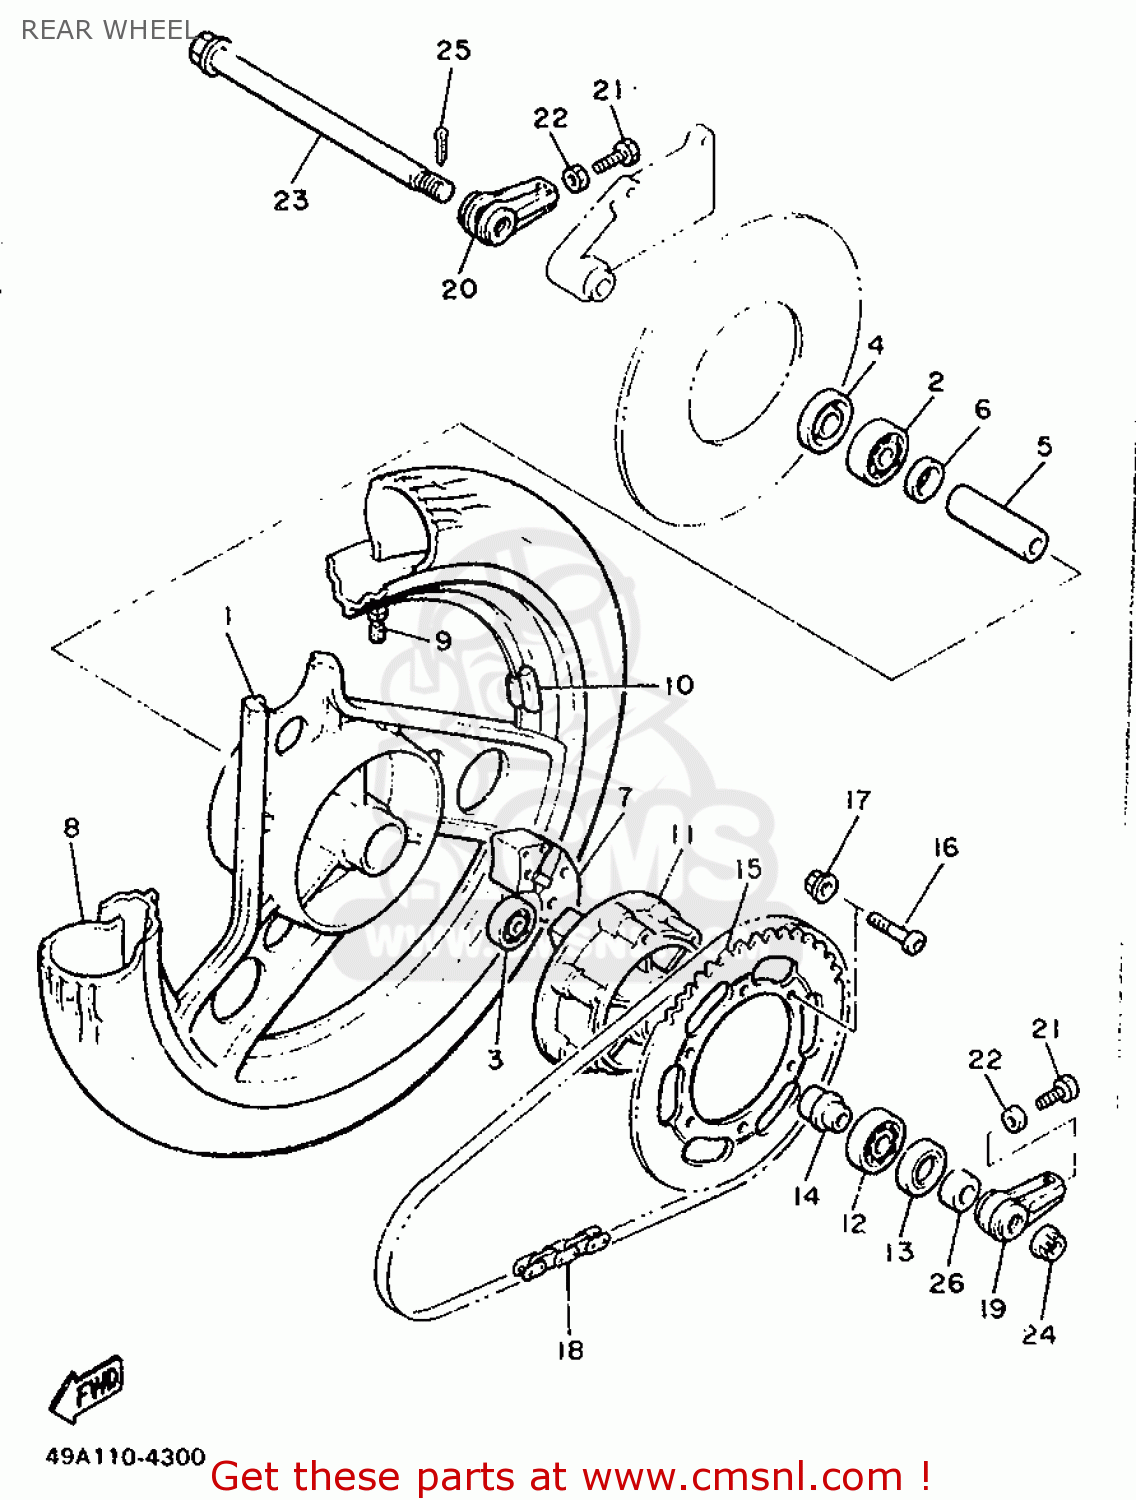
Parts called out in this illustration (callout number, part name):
01	CAST WHEEL, REAR
02	BRG,R-B 6303 47MM 115G NT
03	BRG,R-B 6203RS 40MM 63.3G KY
04	OIL SEAL (25X47X7-801)
05	SPACER (33M)
06	FLANGE, SPACER
07	DAMPER
08	TIRE(49F)
09	VALVE, RIM (3H)
10	BALANCER, WHEEL
11	CLUTCH, HUB
12	BRG,R-B 6304LU 52MM 143G NTN
13	OIL SEAL (29L)
14	COLLAR (33M)
15	SPROCKET, DRIVEN (44T)
16	BOLT, HEXAGON SOCKET HEAD (29L
17	NUT, SELF-LOCKING(1AG)
18	CHAIN(1JR)
19	PULLER, CHAIN 1
20	PULLER, CHAIN 2
21	BOLT(3JD)
22	NUT
23	AXLE, WHEEL
24	NUT, CASTLE (4V7)
25	PIN,COTTER
26	COLLAR (33M)
